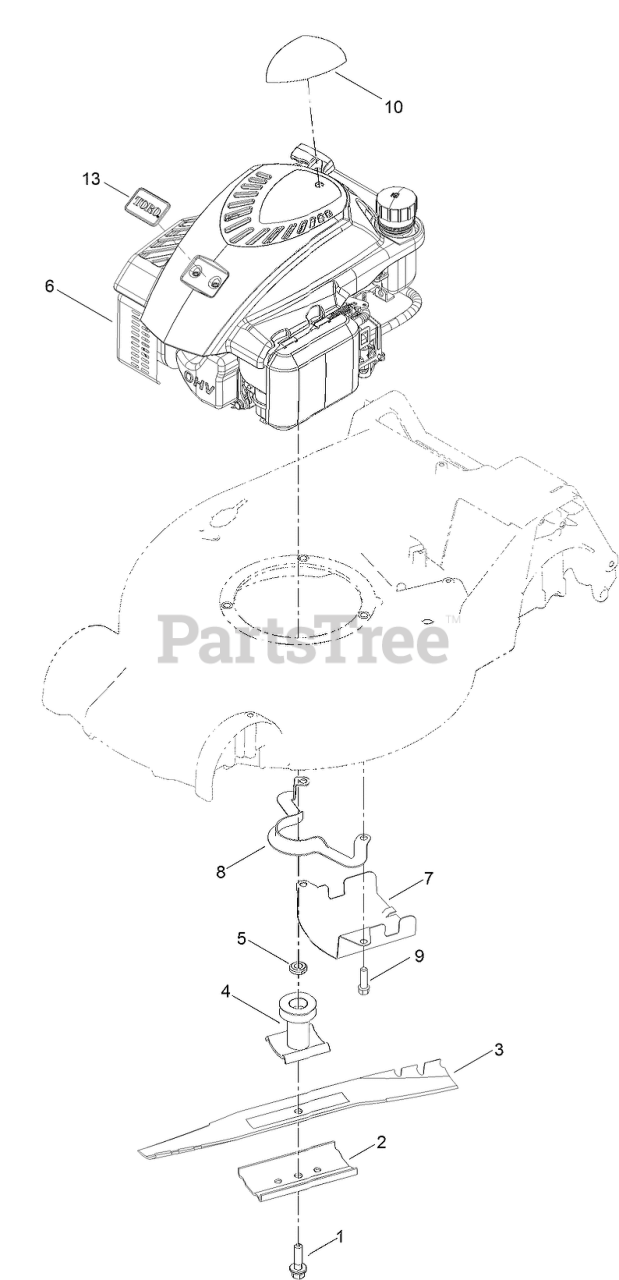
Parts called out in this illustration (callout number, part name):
1	BOLT-BLADE
2	SUPPORT-BLADE
4	DRIVER-BLADE
5	SPACER-DRIVER
7	SHIELD-GRASS
8	GUIDE-BELT
10	DECAL-SHROUD
13	PLATE-LOGO
